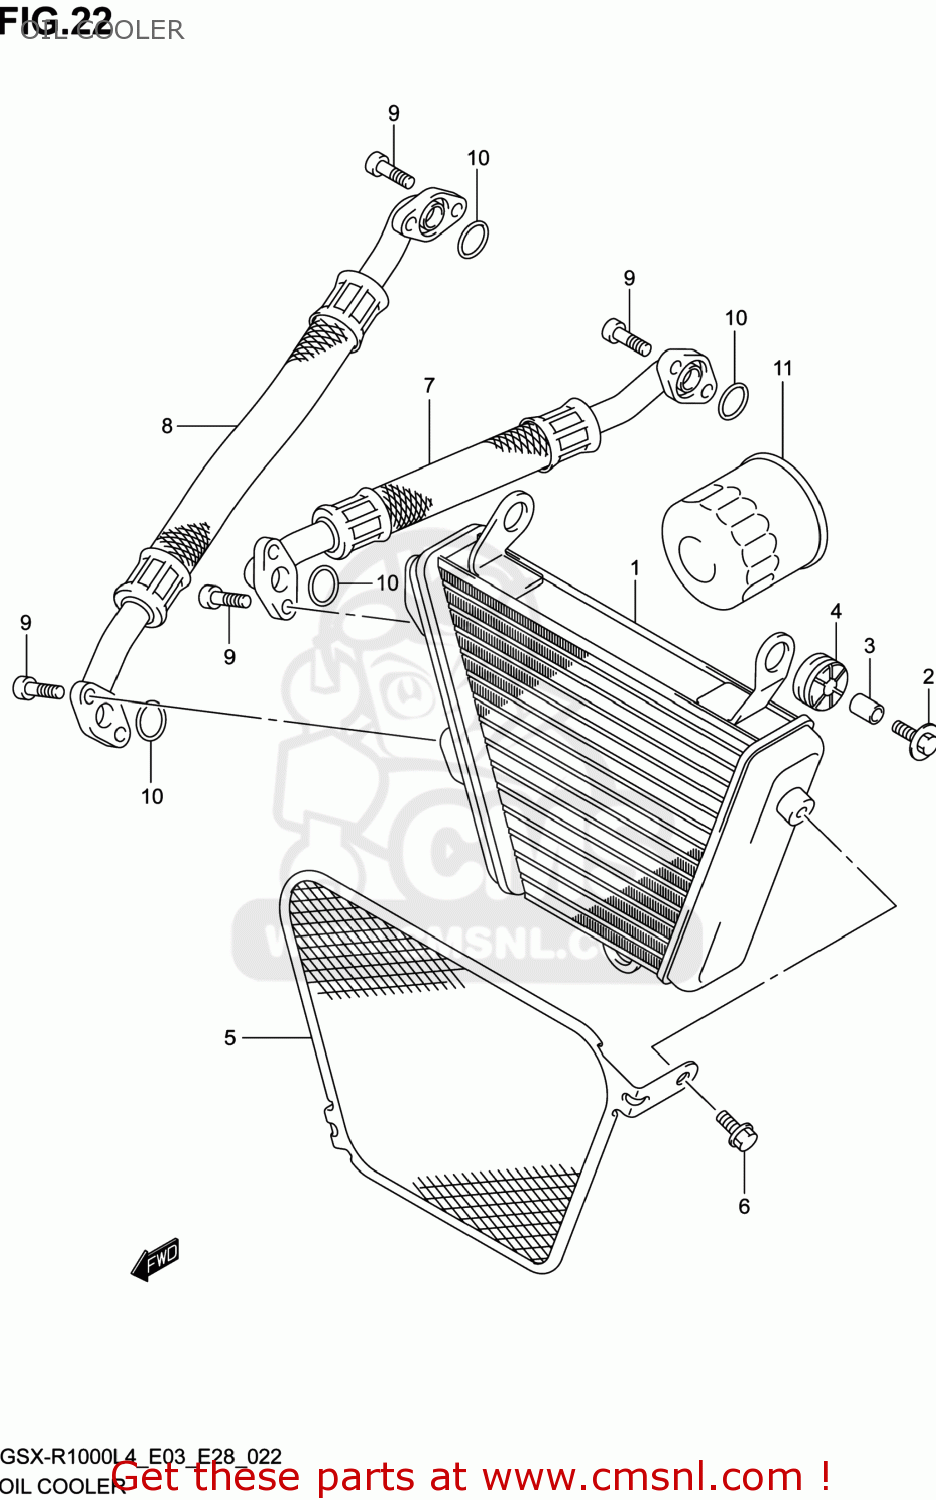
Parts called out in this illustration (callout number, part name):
1	COOLER ASSY,OIL
2	BOLT(6X25)
3	SPACER(6.5X10X12)
4	CUSHION
5	GUARD,OIL COOLER
6	BOLT
7	HOSE,OIL COOLER INLET
8	HOSE,OIL COOLER OUTLETLET
9	BOLT(6X16)
10	O RING(D:2.4,ID:16)
11	FILTER ASSY,ENGINE OIL
